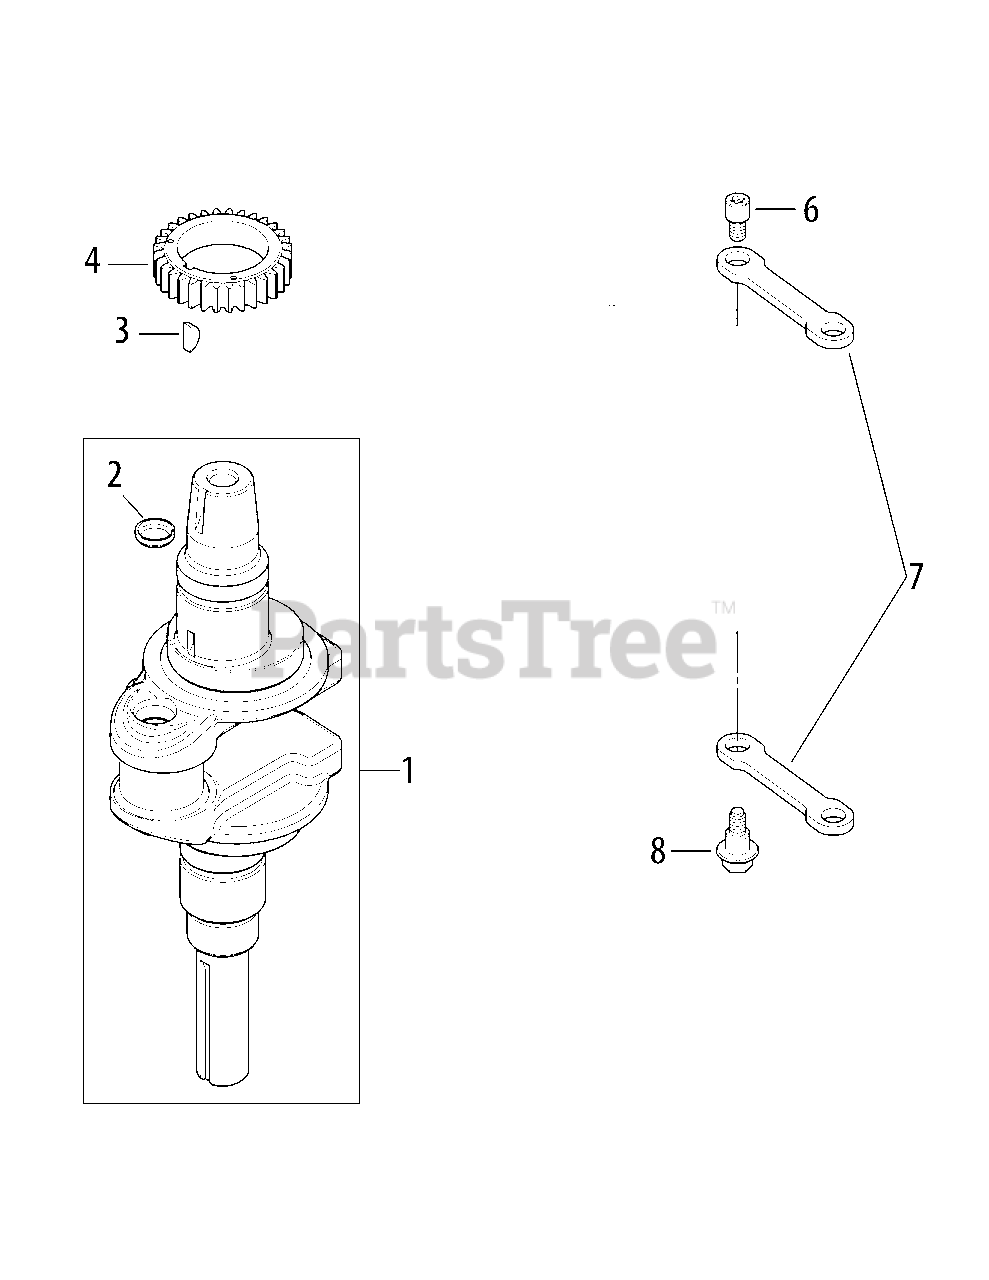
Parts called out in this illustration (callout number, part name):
1	Crankshaft Assembly Kit
3	Key, 3/16 X 5/8
4	Crankshaft Gear
6	Link Pivot Screw
7	Balance Weight Linkage
8	Shoulder Screw
